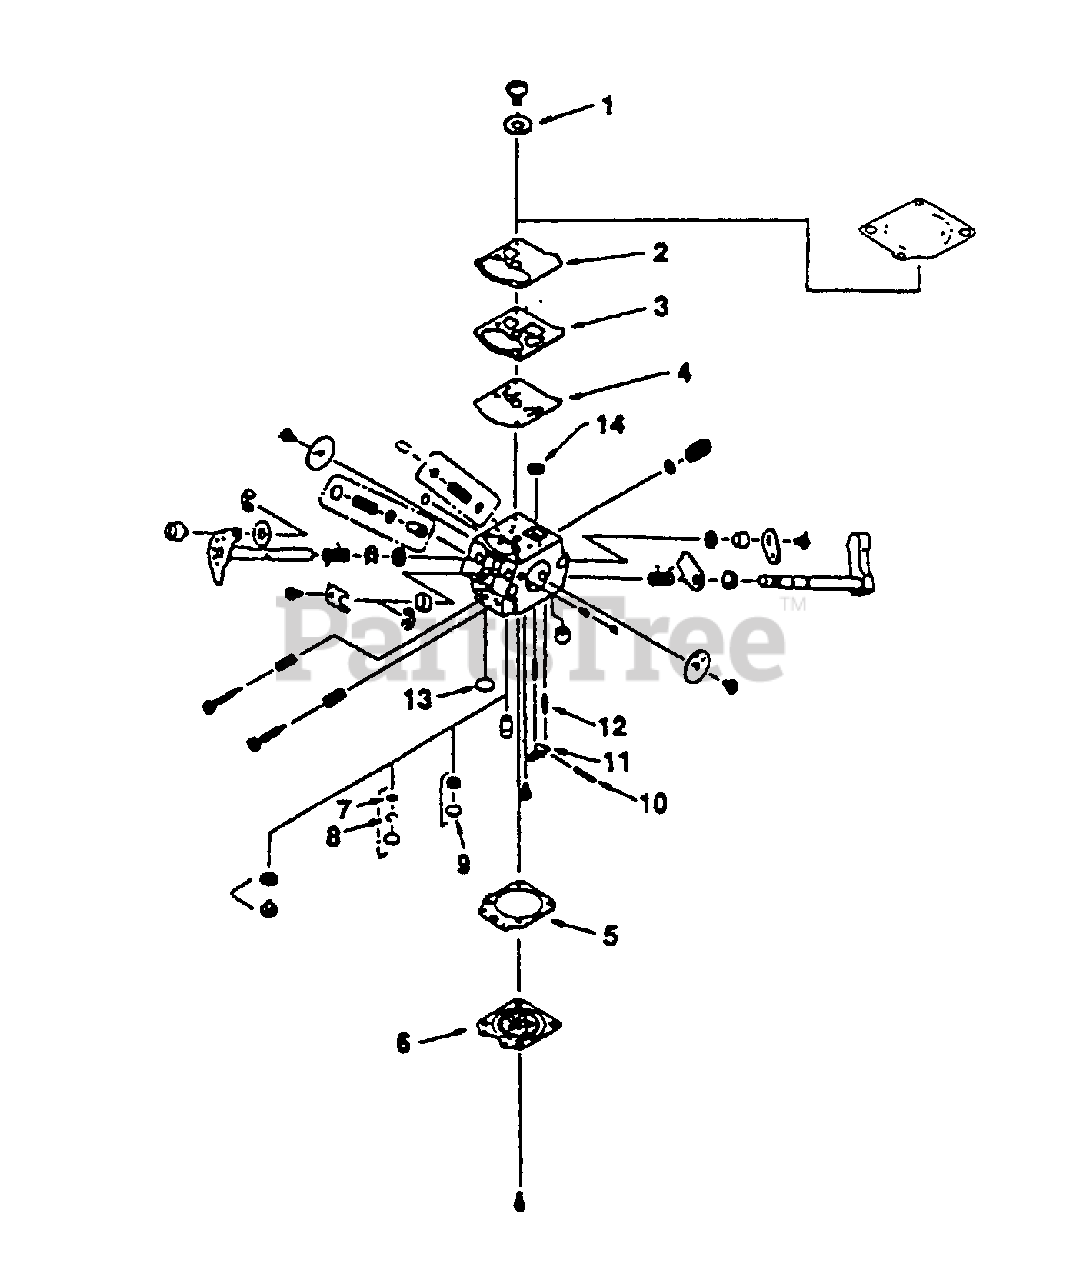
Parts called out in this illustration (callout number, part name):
1	Repair Kit
2	Repair Kit
2	Gasket/Diaphragm Kit
3	Repair Kit
3	Gasket/Diaphragm Kit
4	Repair Kit
4	Gasket/Diaphragm Kit
5	Repair Kit
5	Gasket/Diaphragm Kit
6	Repair Kit
6	Gasket/Diaphragm Kit
7	Repair Kit
8	Repair Kit
9	Repair Kit
10	Repair Kit
11	Repair Kit
12	Repair Kit
13	Repair Kit
14	Repair Kit
